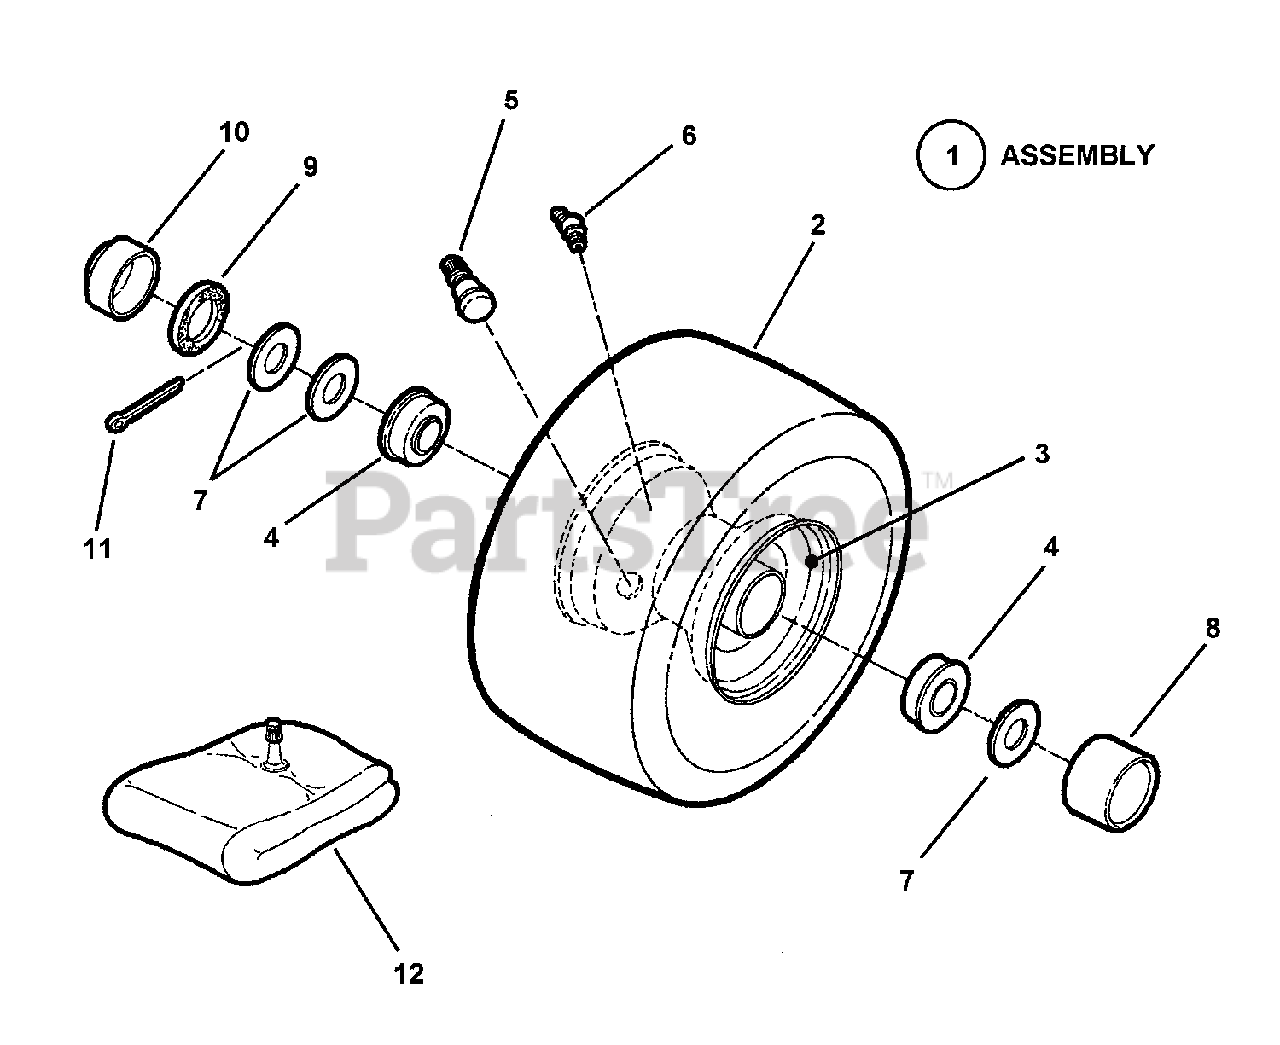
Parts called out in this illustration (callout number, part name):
1	ASSEMBLY, Front Tire & Rim (11.0") (Complete)
2	TIRE, 11 x 4.00-4 (Kenda)
3	RIM (For 11.0 x 4.0 x 4 Tire)
4	BALL BEARING, Flange (3/4" I.D.)
5	VALVE STEM, Snap In
6	* LUBE Fitting, Straight (for 3/16" hole)
6	* LUBE Fitting, Straight (for 1/4" hole)
6	* LUBE Fitting, 90 Degree, Ball Check (for 1/4" hole)
6	* LUBE Fitting, 90 Degree, Ball Check (for 5/16" hole)
7	WASHER, .77 x 1.13 x .06 Flat
8	HUB CAP
9	FELT SEAL
10	CAP, Dust
11	COTTER PIN, 5/32 x 1"
12	TUBE, Inner (For 4.10/3.50 x 4 Tire)
